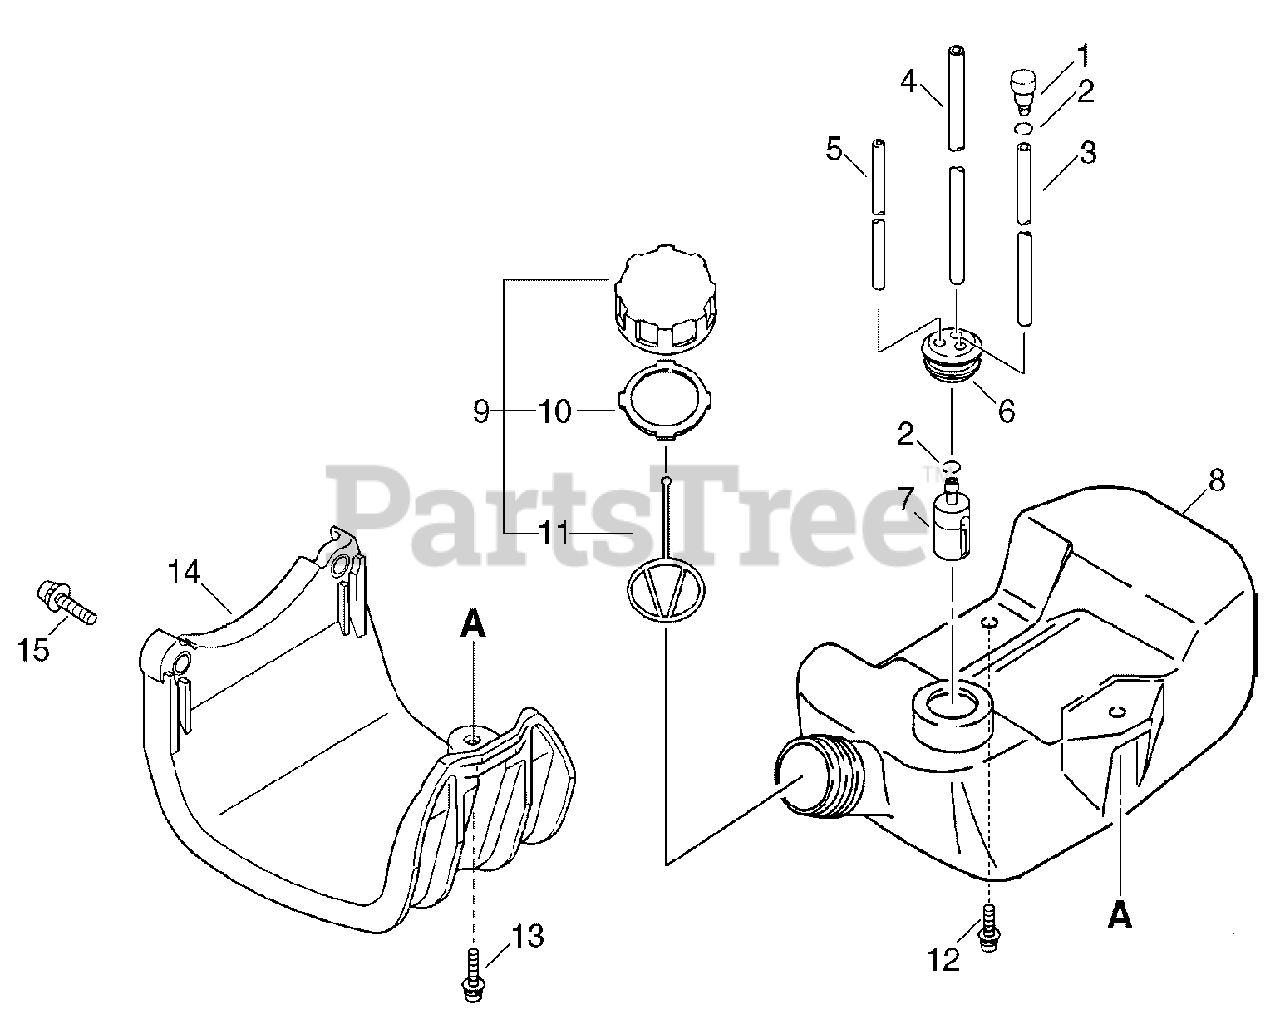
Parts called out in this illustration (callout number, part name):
1	VENT ASSY
2	CLIP 6.5 MM
3	PIPE, FUEL 3×6×100
4	PIPE, FUEL 3×6×170
5	PIPE, FUEL 3×6×60 CLEAR
6	GROMMET, FUEL
7	FILTER, FUEL
8	TANK, FUEL
9	CAP ASSY, FUEL
10	GASKET, FUEL CAP
11	CONNECTOR, CAP L= 100 MM
12	SCREW 5×16
13	SCREW 5×20
14	GUARD, FUEL TANK
15	BOLT 5×22
